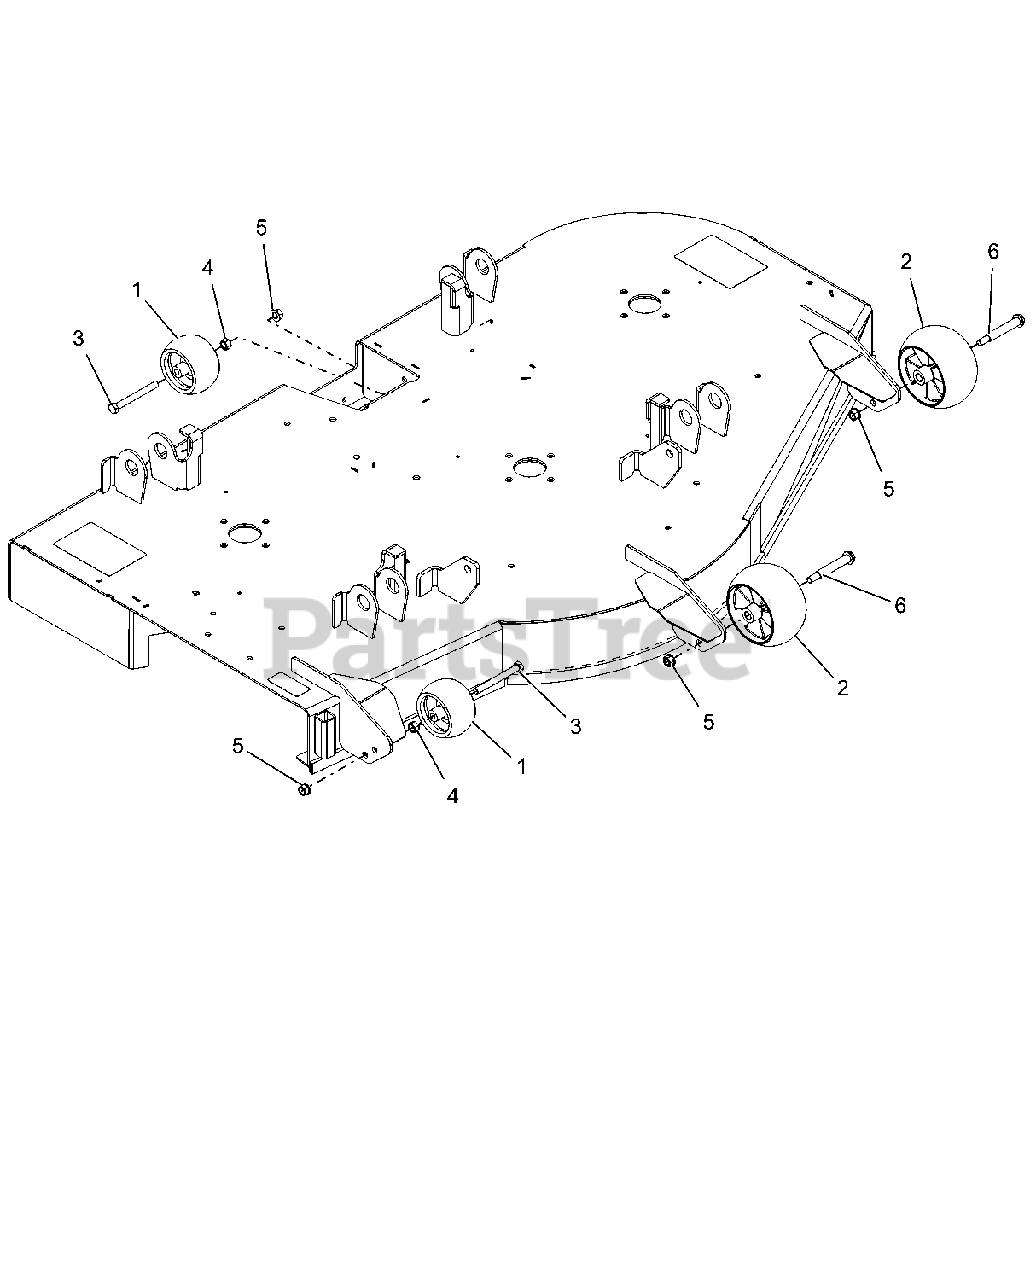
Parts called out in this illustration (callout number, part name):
2	ANTI-SCALP WHEEL - 5XOS
3	BLT-HEX .38-16X3.50 GR5 YWZC
4	NUT-HEX .38-16 YWZC
5	NUT, LK-TOP-FLG .38-16 YWZC
6	BLT-SHLDR .38-16X2.50 HWH G5YZ
